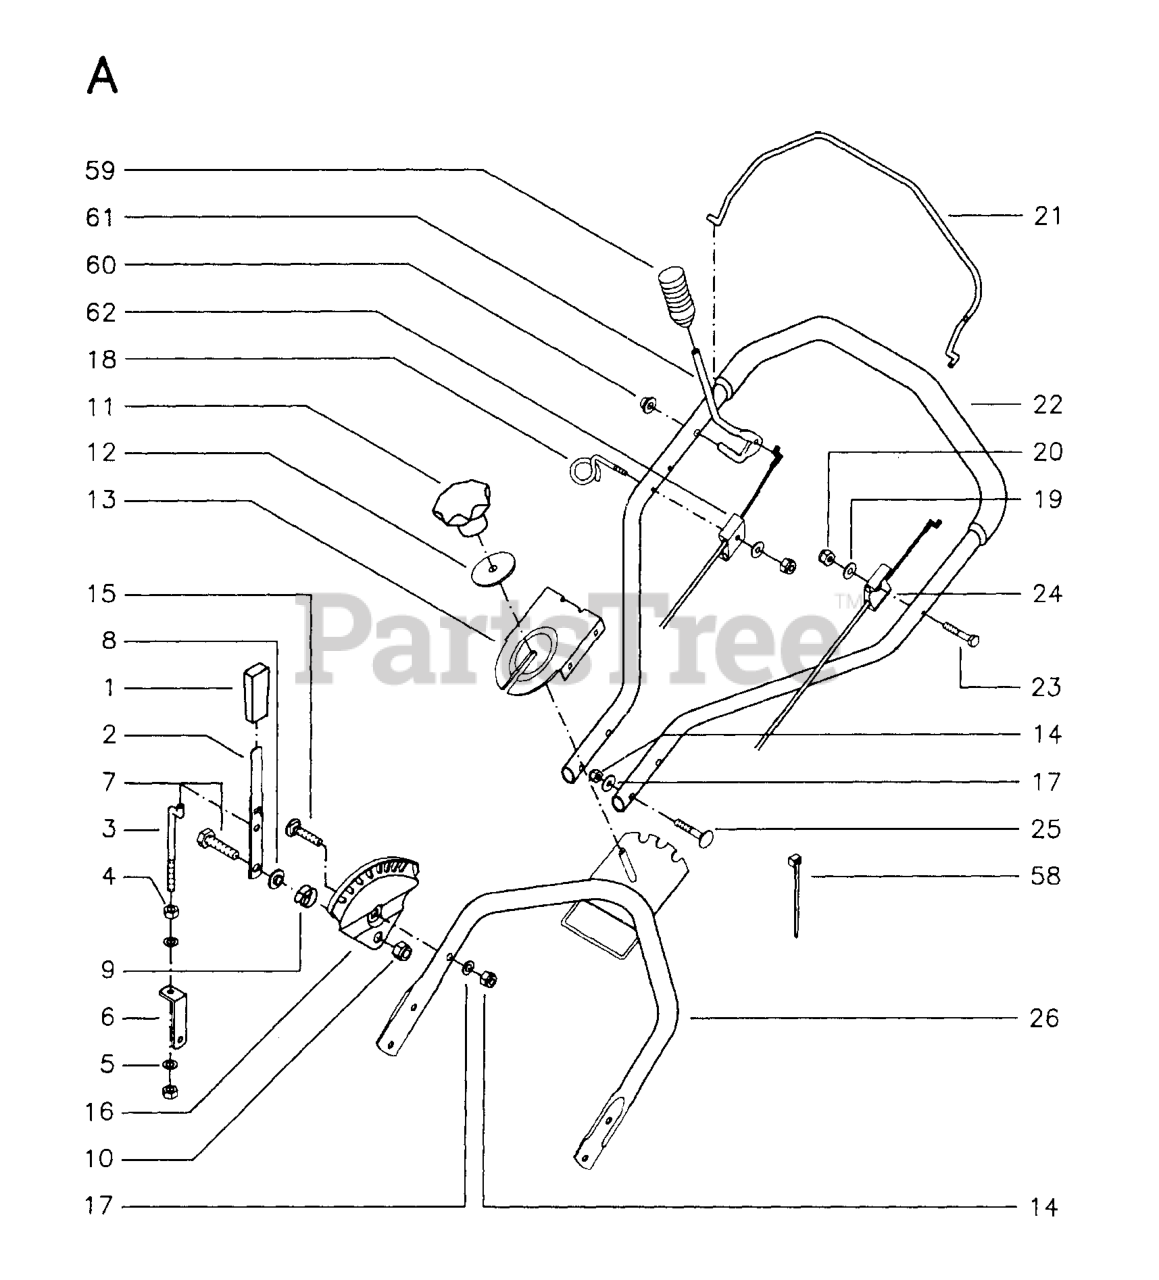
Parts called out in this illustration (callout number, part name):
2	CLUTCH ARM
4	NUT
5	STAR WASHER
9	PRESSURE SPRING
14	LOCKNUT M8
16	INDEXPLATE
17	WASHER - 15X7.3X1.6
20	LOCKNUT M6
23	BOLT FLANGE
